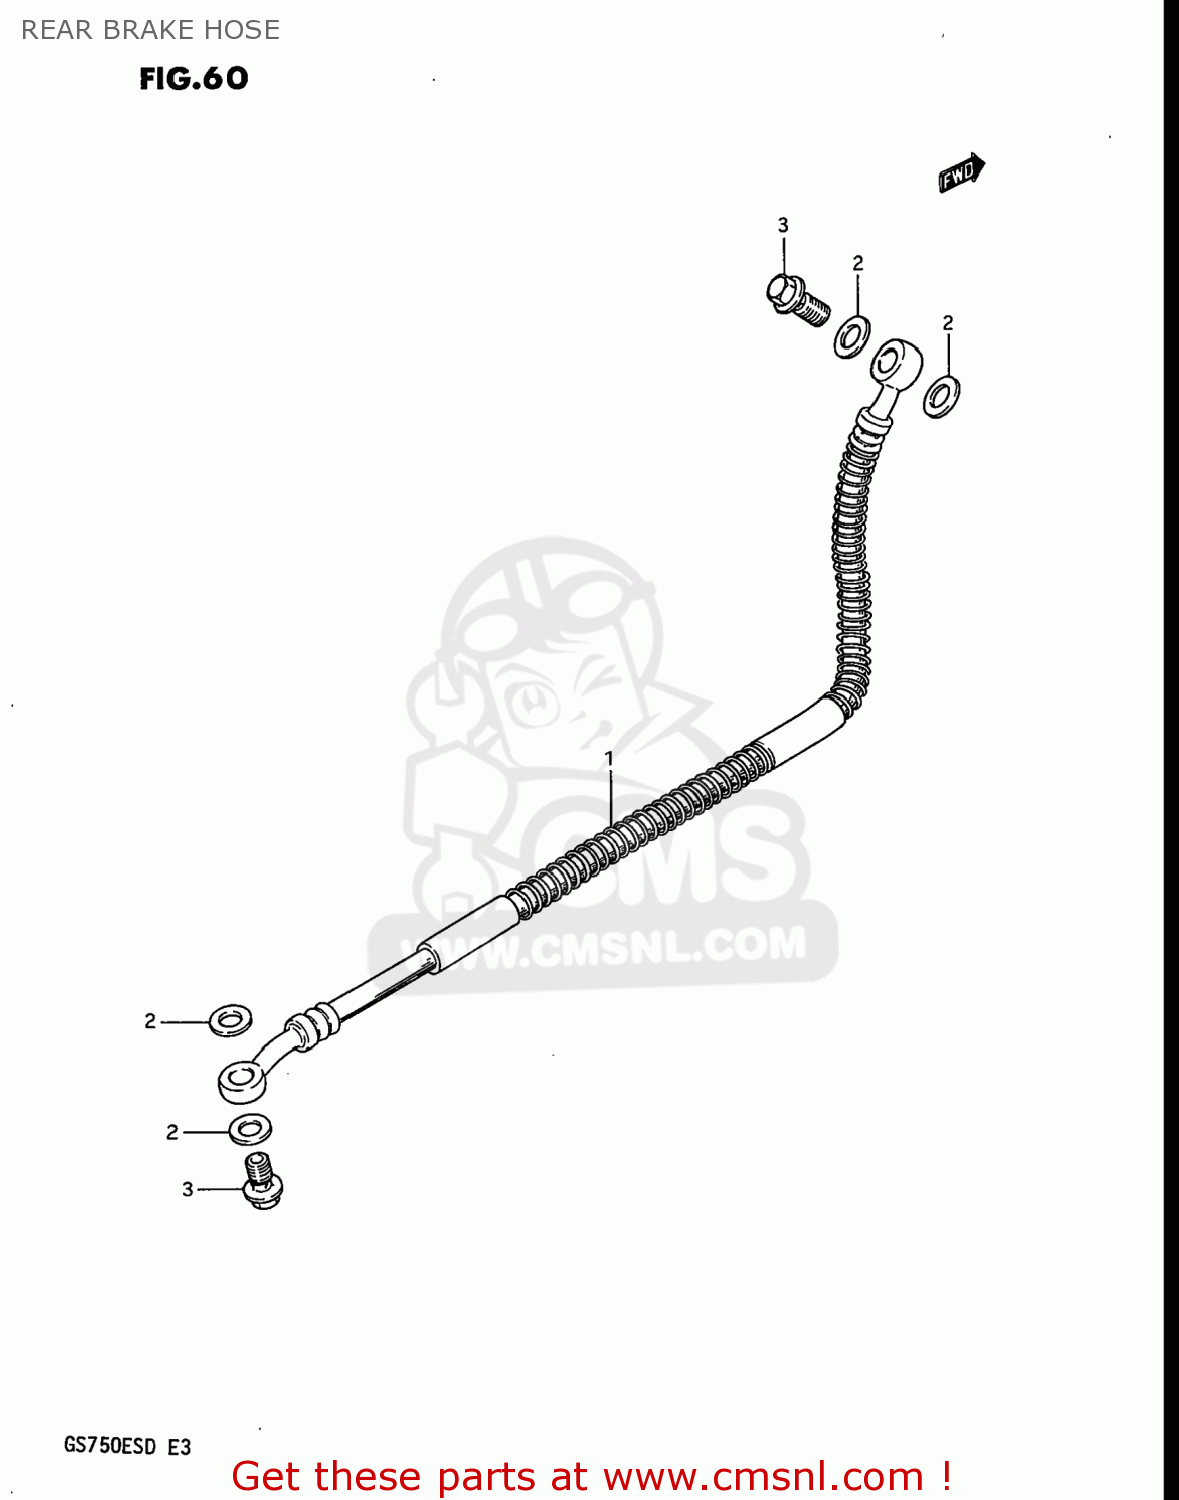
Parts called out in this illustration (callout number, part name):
1	HOSE,REAR BRAKE
2	WASHER
3	BOLT UNION
